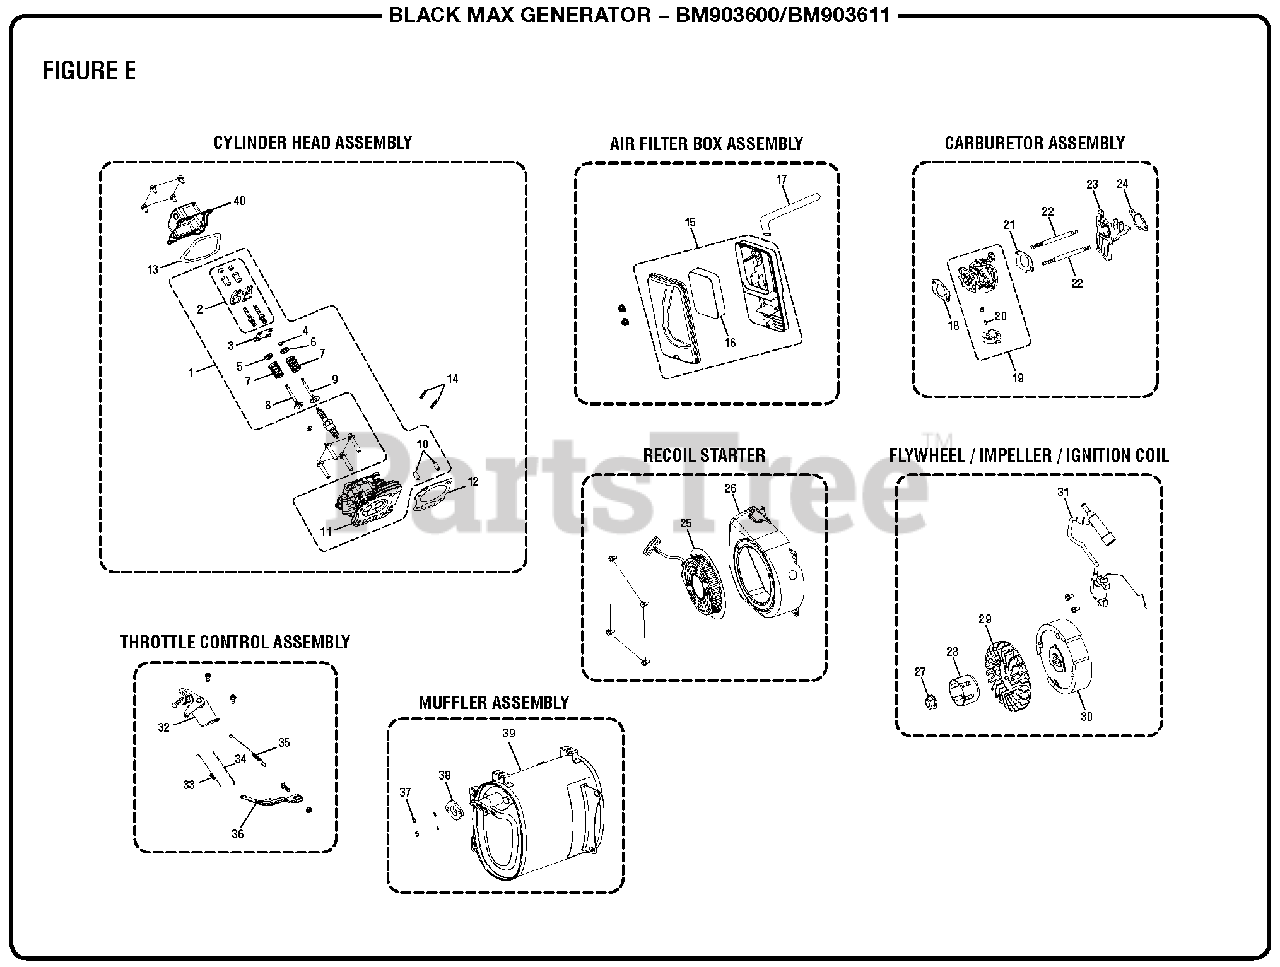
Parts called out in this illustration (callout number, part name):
1	Cylinder Head Assembly
2	Rocker Assembly
3	Guide Plate
4	Rotator
5	Valve Spring Seat (Intake)
6	Valve Spring Seat (Exhaust)
7	Valve Spring
8	Intake Valve
9	Valve Exhaust
10	Dowel Pin
11	Cylinder Head
12	Cylinder Head Gasket
13	Cylinder Head Cover Gasket
14	Threaded Stud
15	Air Cleaner Assembly
18	Spacer
19	Carburetor Assembly
20	Needle Valve
21	Carburetor Gasket
22	Threaded Stud
23	Carburetor Insulator
24	Intake Gasket
25	Recoil Starter
26	Recoil Starter Cover
27	Nut
28	Starter Pulley
29	Recoil Starter Fan
30	Flywheel Assembly
31	Ignition Coil Assembly
32	Throttle Assembly
33	Governor Spring
34	Governor Rod
35	Throttle Return Spring
36	Governor Arm
37	Hex Nut
38	Exhaust Gasket
39	Muffler Assembly
40	Valve Cover
